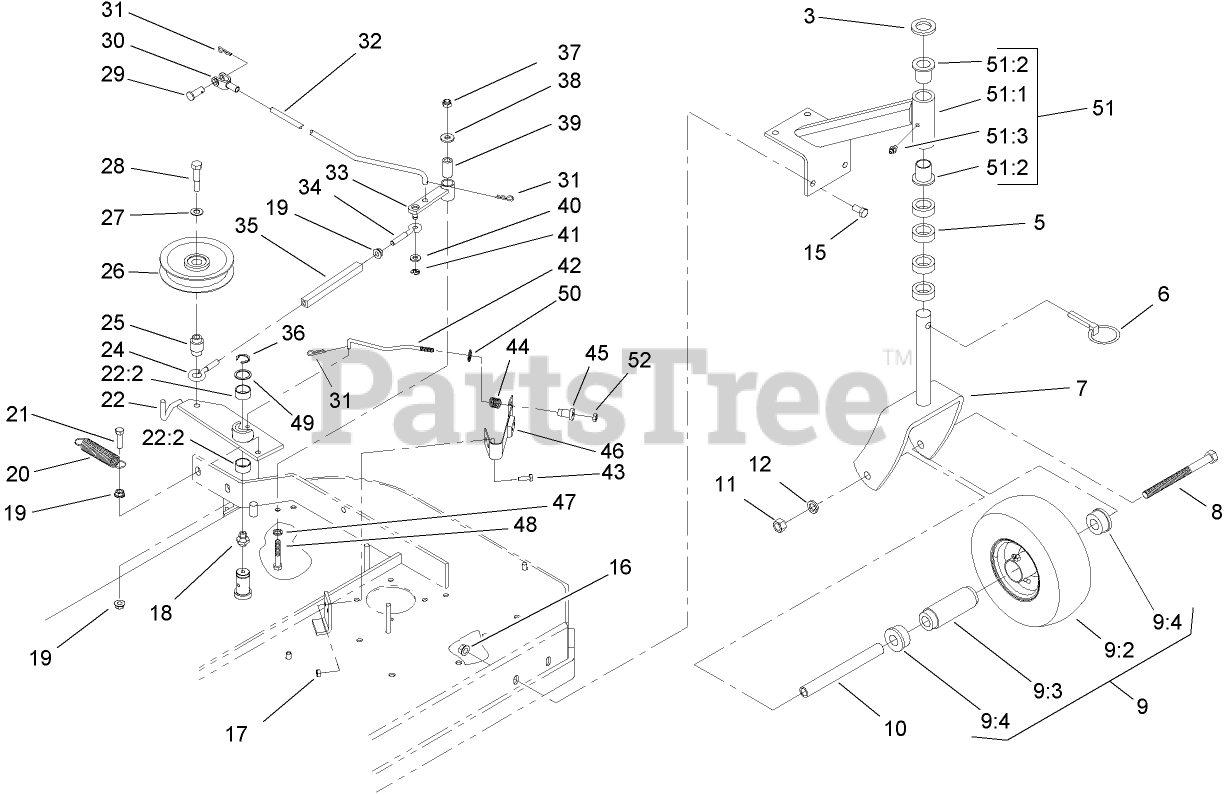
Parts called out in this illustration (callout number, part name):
3	WASHER-FLAT
5	SPACER-CASTER
7	FORK
8	SCREW-HH
9	WHEEL AND TIRE ASM
9:3	BEARING
9:4	BUSHING
10	SPACER
11	NUT-HH
12	WASHER-LOCK
15	SCREW-HH
16	NUT-HHF, WHIZ
17	NUT-LOCK, NI
18	FITTING-GREASE
19	NUT-HF
20	SPRING-EXTENSION
21	SCREW-HH
22	Idler Arm ASM
22:2	SLEEVE-BEARING
24	EYEBOLT-THREAD, LH
25	BUSHING-ENGAGEMENT
26	PULLEY-IDLER
27	WASHER-BELLEVILLE
28	SCREW-HH
29	PIN-CLEVIS
30	YOKE-ADJUSTABLE
31	PIN-COTTER
32	ARM-ASSIST, LINKAGE
33	ARM-ASSIST
34	EYEBOLT-THREAD, RH
35	BODY-TURNBUCKLE
36	RING-RETAINING, EXT
37	NUT-LOCK, NI
38	WASHER-FLAT
39	TUBE-PIVOT
40	WASHER-PLAIN
41	RING-RETAINING, EXT
42	ROD-BRAKE
43	SCREW-HH
44	SPRING-COMPRESSION
45	SPACER-FLANGED
46	PAD AND SPRING ASM
47	WASHER-SPRING
48	SCREW-HH
49	WASHER-SPINDLE
50	RING-PUSH ON
51	SUPPORT ASM
51:1	Support-Caster
51:2	BEARING-FLANGED
51:3	FITTING-GREASE
52	NUT-LOCK, NI
